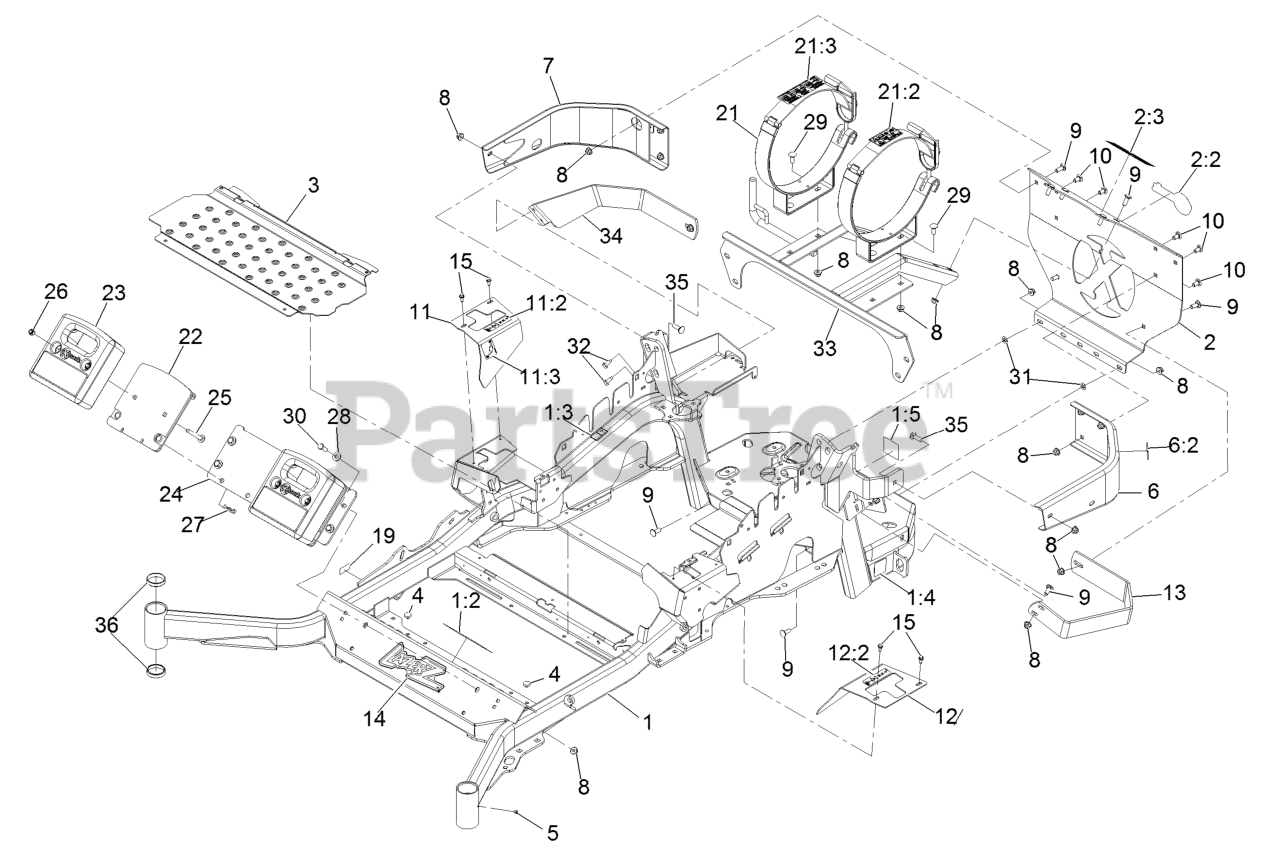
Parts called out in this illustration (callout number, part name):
1	MAINFRAME ASM
1:2	DECAL-WARNING
1:3	DECAL-WARNING, SLOPE
1:4	DECAL-HAZARD, PINCHED FINGER
1:5	DECAL-SPARK ARRESTER
2	REAR GUARD-LP W/DECALS
2:3	Decal-LPG Fuel TankReplacement
6	LH BUMPER ASM
6:2	DECAL-WARNING
7	BUMPER-RH
8	NUT-HF, NI
9	SCREW-CARR
10	SCREW-CARR
11	RH MOTION CONTROL COVER ASM
11:2	DECAL-CONTROL, MOTION
11:3	DECAL-PARK BRAKE, CE
12	LH MOTION CONTROL COVER ASM
12:2	DECAL-CONTROL, MOTION
13	GUARD-MUFFLER
14	DECAL,LAZER MODEL
15	SCREW-HWH
19	Decal-Patent Ttco.Com
21	TANK BRACKET ASM (SET)
21:2	Decal-LPG Warning
21:3	Decal-LPG Tank Spec
22	WLD,WEIGHT MOUNT
23	WEIGHT,CAST 36LB
24	PLATE,WEIGHT ASM MOUNT
25	SCREW-CARR
26	NUT-LOCK, NI
27	PIN-HAIR
28	WASHER-BELLEVILLE
29	BOLT-CARR
30	SCREW-HH
31	NUT-PUSH
32	Screw-HWH 5/16-18 X 3/4 Tf
33	SUPPORT-TANK
34	STRAP-GUARD
35	BOLT-CARR
36	CUP-BEARING
